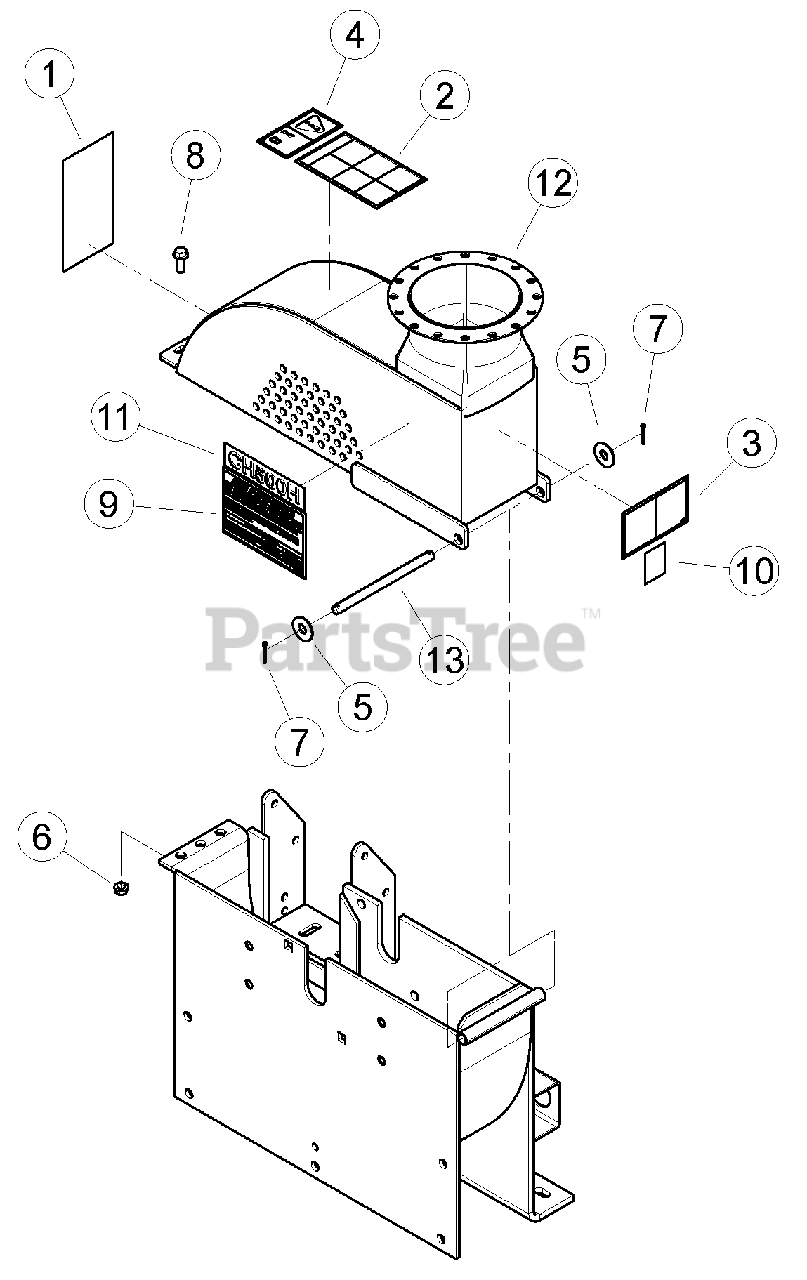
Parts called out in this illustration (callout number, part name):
1	DECAL, KNIFE ACCESS ISO
2	DECAL, OPERATING INSTRUCTIONS ISO
3	DECAL, DISCHARGE ISO
4	DECAL, MAINTENANCE ISO
5	WASHER, 1/2 FLAT CMS F1 5ANS
6	NUT, 3/8-16 SERRATED FLANGE
7	PIN, 1/8 X 1.00 ZP COTTER
8	BOLT, 3/8-16 X 1 SERRATED FLANGE GR5
9	DECAL, FLOW RATE HYDRAULIC
10	DECAL, ECHO BEARCAT QR CODE
11	DECAL, MODEL CH500H
12	WELDMENT, TOP CHIPPER HOUSING
13	SHAFT, CHIPPER TOP PIVOT
